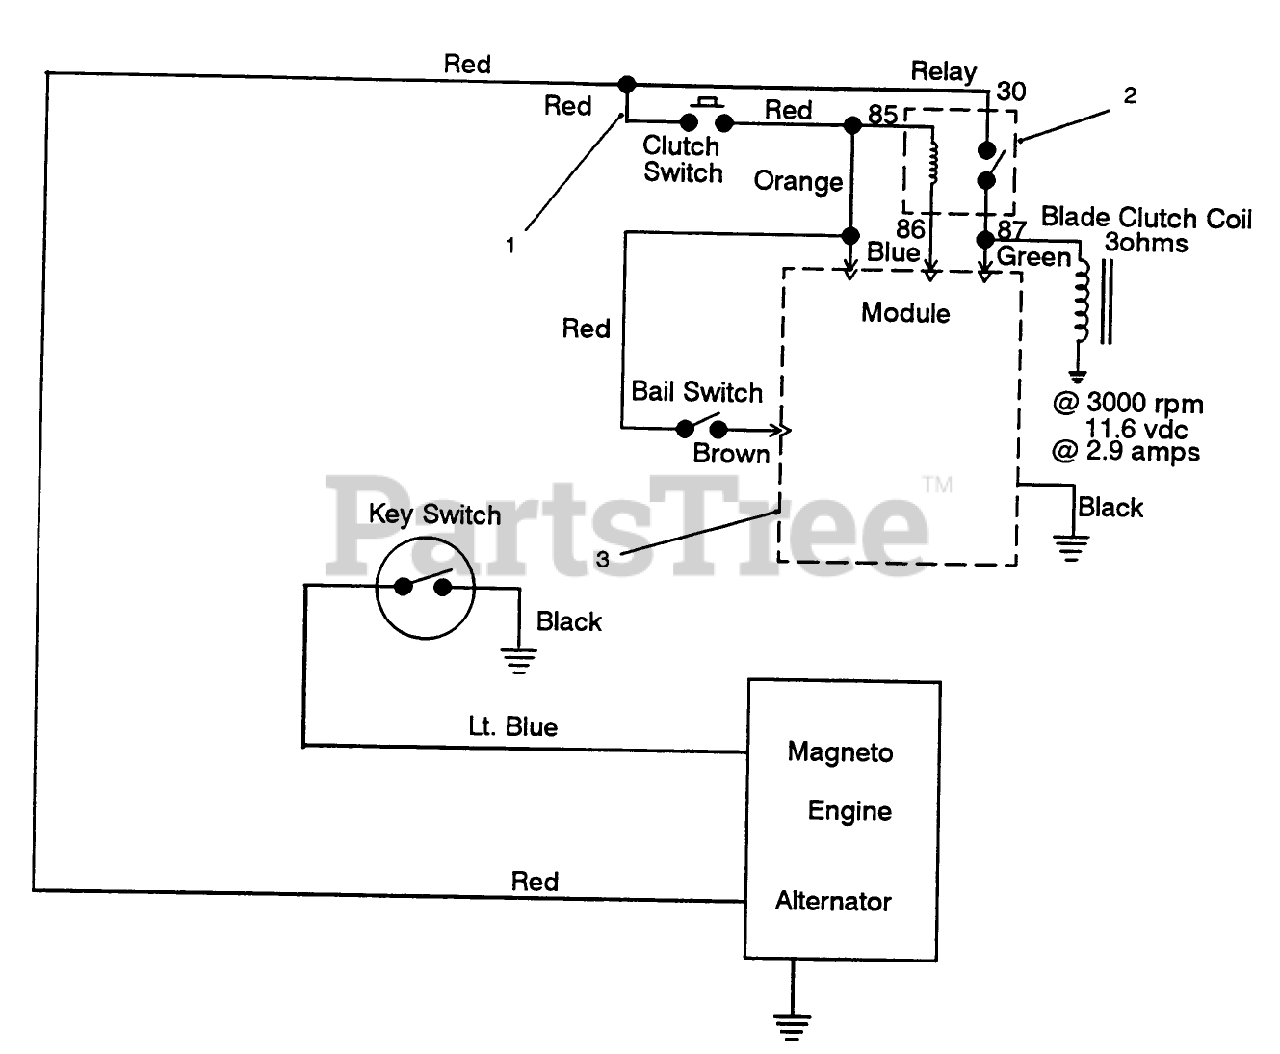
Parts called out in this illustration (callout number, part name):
1	WIRE HARNESS
2	RELAY
3	Module
